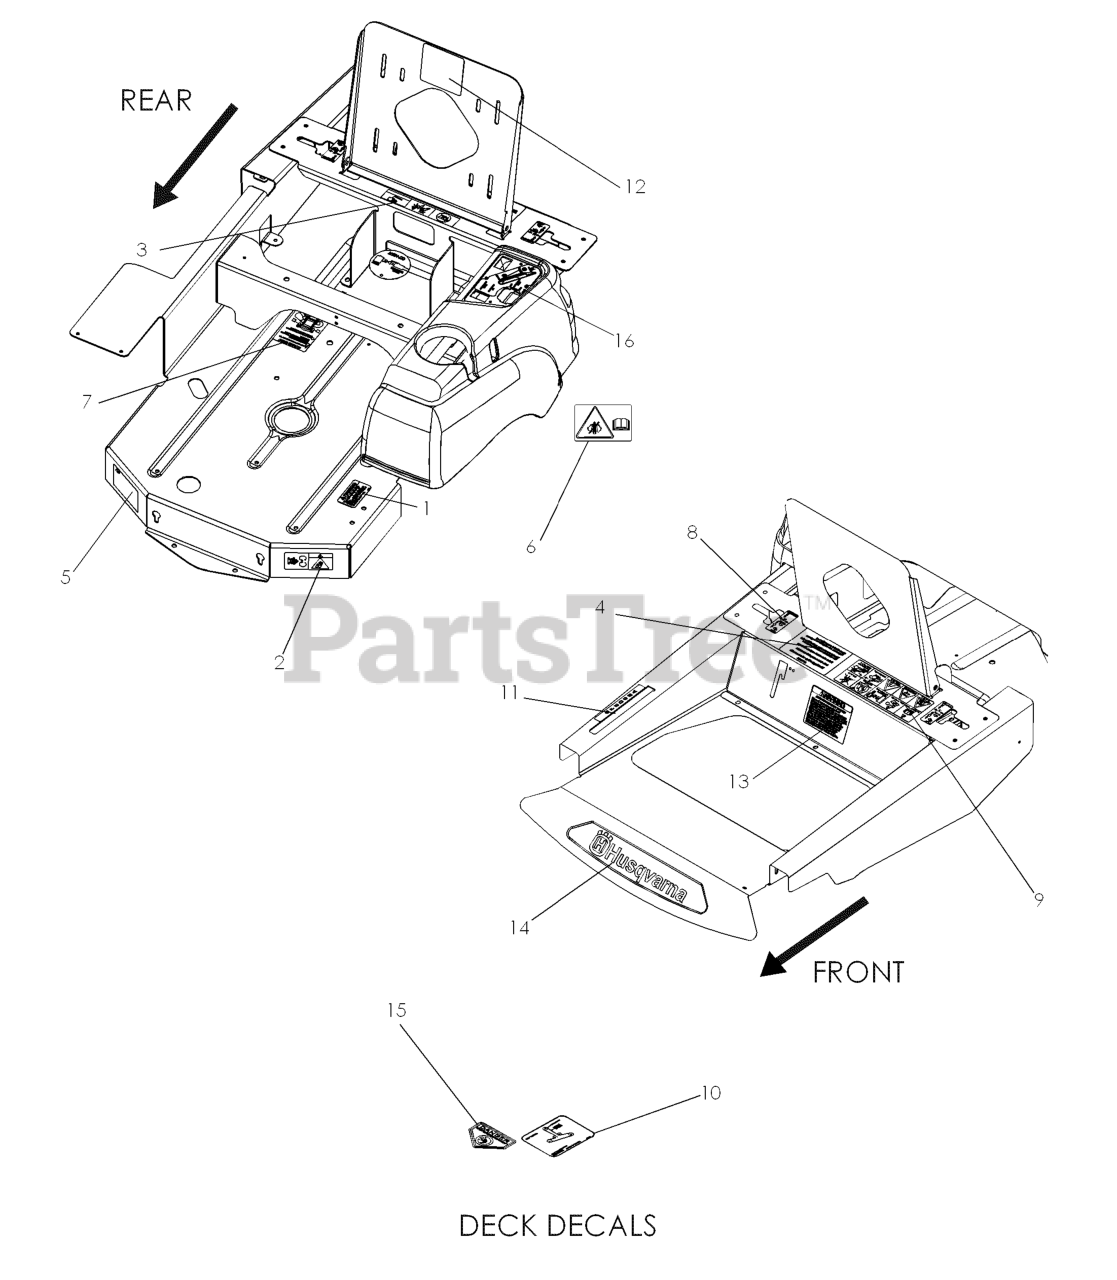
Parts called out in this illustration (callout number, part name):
1	DECAL, PROP. 65
2	DECAL, BELT DRIVE
3	EURO DECAL-BATTERY WARNIN6
4	DECAL, START
5	DECAL, DO NOT TOW
6	DECAL, EXITING MOWER
7	DECAL, SERVICE
8	DECAL, MOTION CONTROL
9	DECAL, SAFETY WARNING
10	DECAL, BELT
10	DECAL, BELT ROUTING
11	DECAL, HEIGHT
12	DECAL, CUSTOMER RESPNSIBILITY
13	DECAL, WARNING
14	DECAL, HUSQ 12" BLUE
15	DECAL, CPSC
16	DECAL, IGNITION CONSOLE
